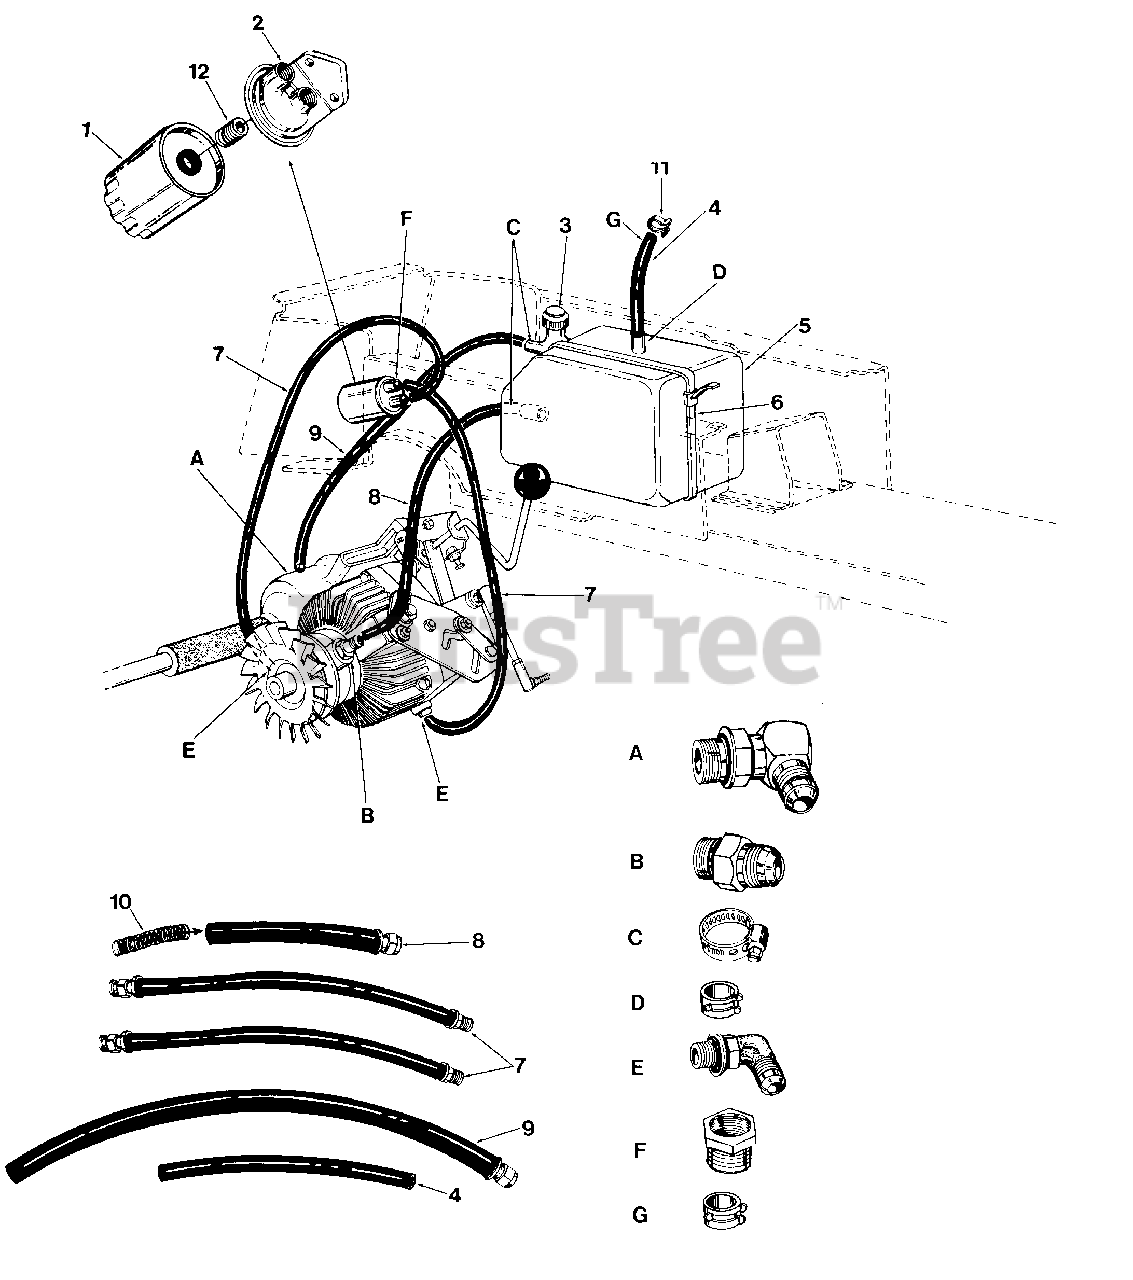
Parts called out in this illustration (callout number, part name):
1	Oil Filter
2	Filter Base
3	Oil Reservoir Cap
4	Gas Line-13" Lg.
5	Oil Reservoir
6	Cable Tie 34.25" Lg.
7	Hose Ass'y. 3/8" I.D. x 16.5" Lg.
8	Hose Ass'y. 5/8" I.D. x 9" Lg.
9	Hose Ass'y. 1/2" I.D. x
10	Spring-Part of Ref. No. 8
11	Wire Retainer
12	Expansion Plug 1-3/16"
